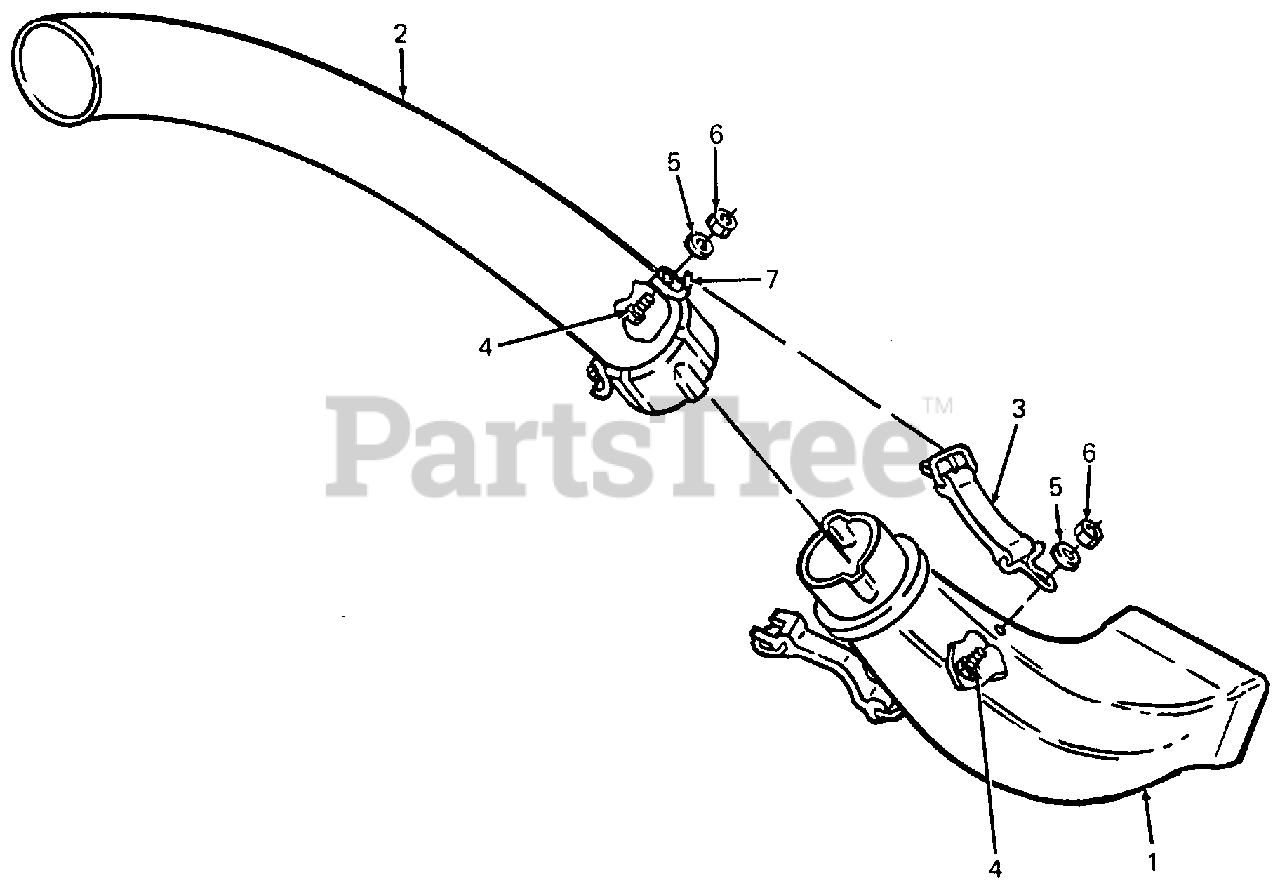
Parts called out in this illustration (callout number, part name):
1	Chute, Discharge
2	Elbow, Catcher
3	Strap Assy, Retainer
4	Screw, Hex, 1/4-20 X .50 Lg
5	Washer, Spring, .265 X .562
6	Nut, Hex Insert Lock, 1/4-20
7	Hook Bracket, Retainer
